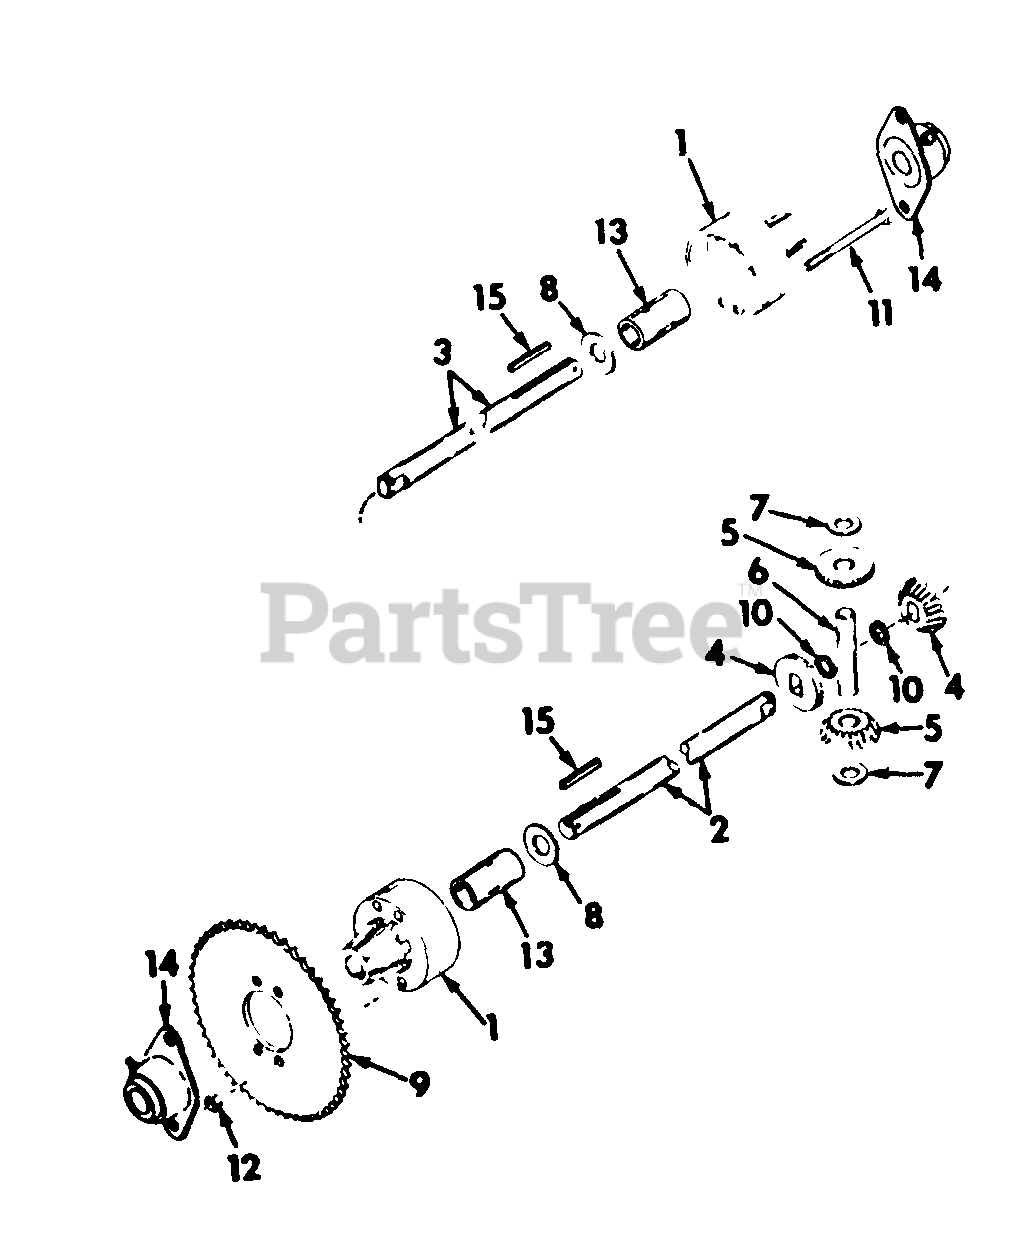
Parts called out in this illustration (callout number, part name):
1	HOUSING, DIFFERENTIAL CARRIER -SPROCKET SIDE-
2	AXLE -8-27/32 IN. LONG-
3	AXLE -21-55/64 IN. LONG-
4	GEAR. BEVEL -16 T
5	GEAR. PINION -16 T
7	WASHER, THRUST BRG RACE
9	SPROCKET - 45 T
10	RING. RETAINER
11	SCREW, 5/16-18 SPECIAL
12	NUT, 5/16-18 LOCK
14	BEARING, REAR AXLE
14	BEARING. REAR AXLE
15	KEY, 3/16 X 1-3/4 SQ PARALLEL
